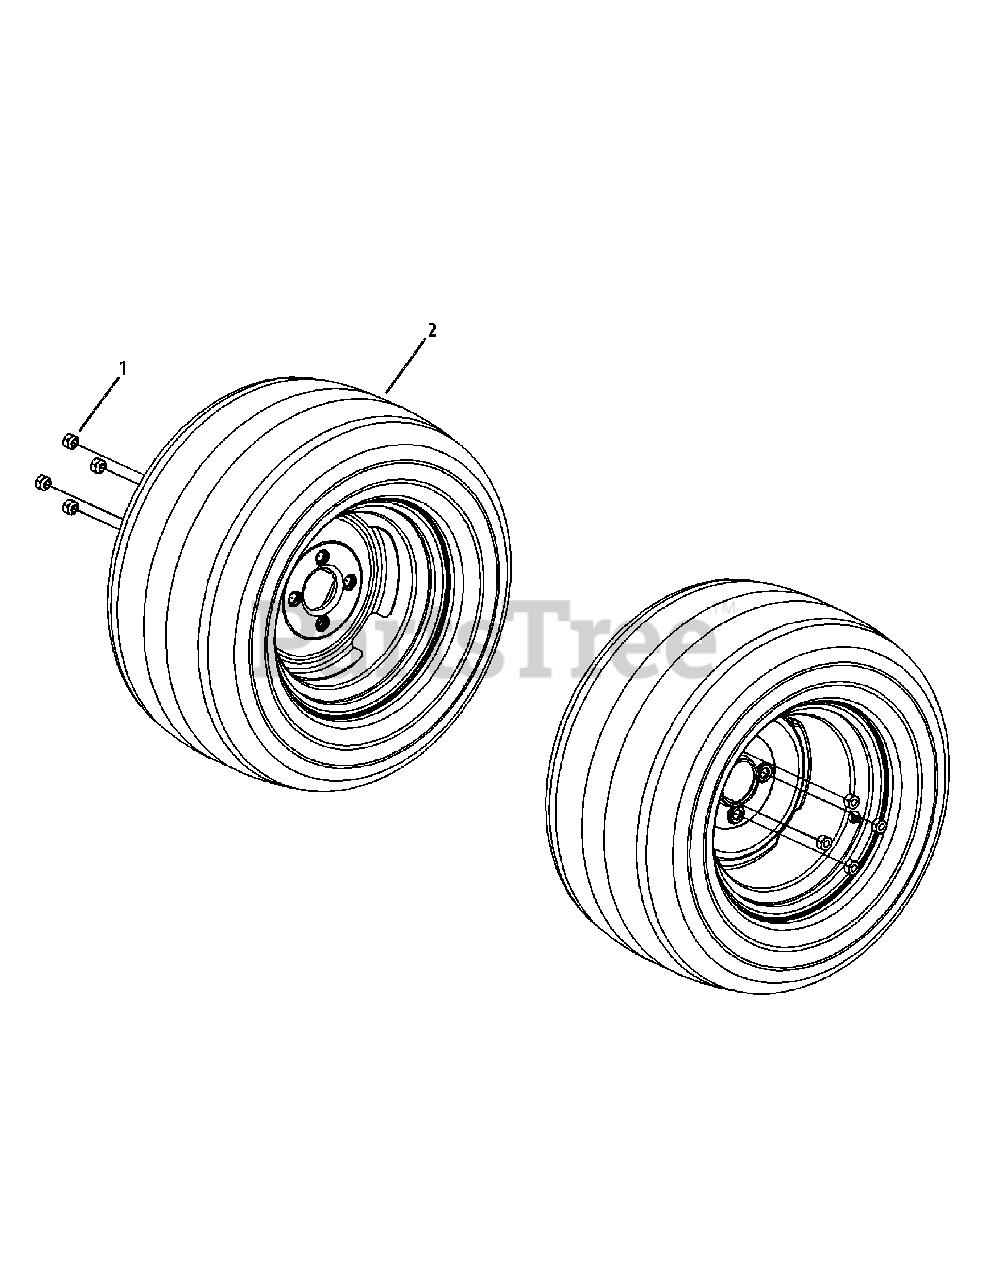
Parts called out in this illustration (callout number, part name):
1	Lug Nut, 1/2-20
2	Wheel Assembly, 9.5-12, Beige
2	Tire, 9.5-12
2	Wheel Assembly, 24 x12-12, Beige
2	Tire, 24 x 12-12
2	Wheel Assembly, 24 x 12-12, Turf Saver
2	Tire, 24 x 12-12, Turf Saver
